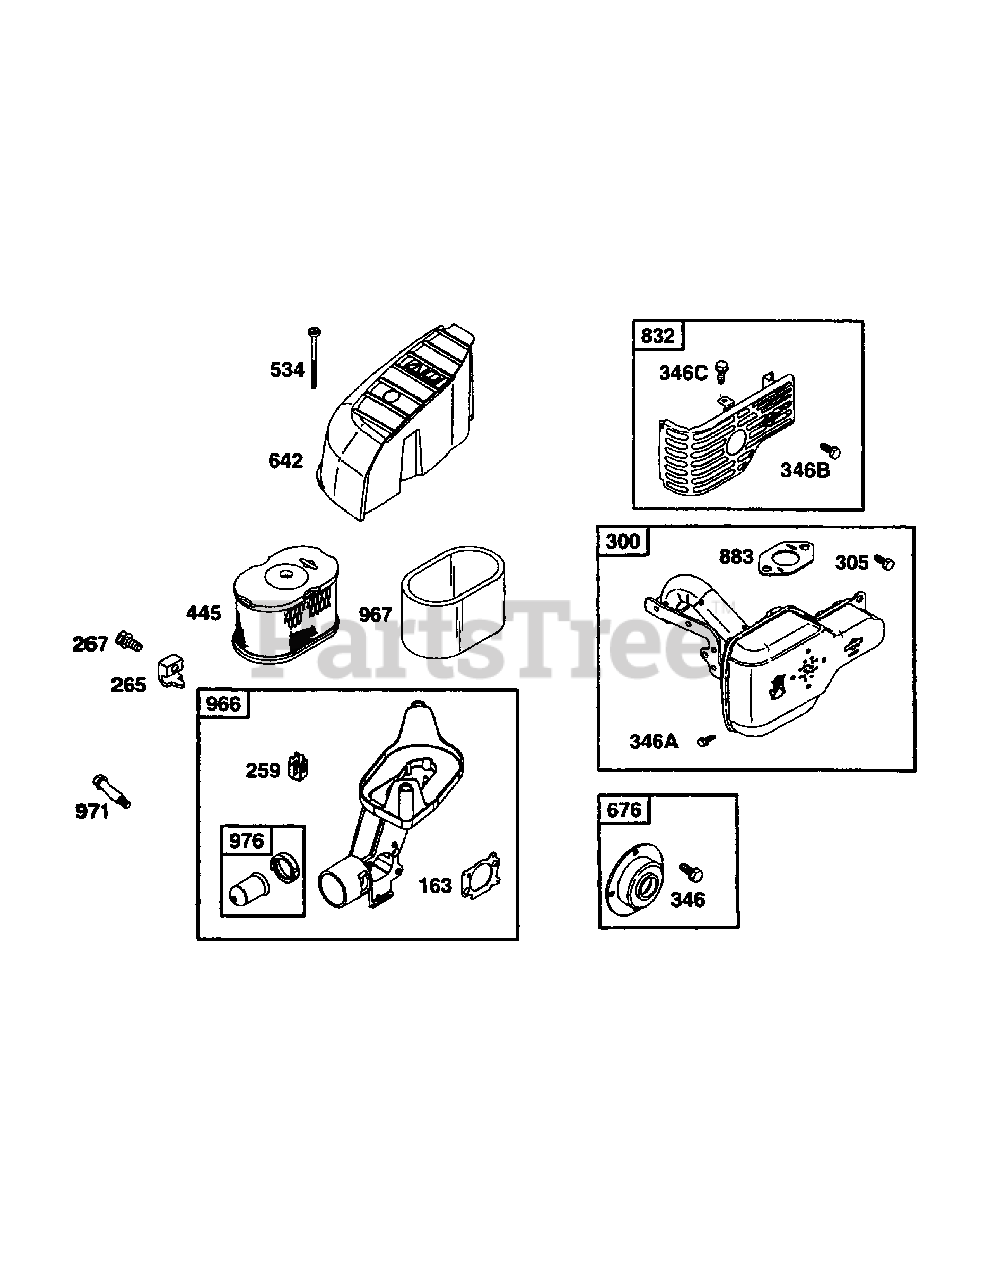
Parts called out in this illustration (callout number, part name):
163	Air Cleaner Gasket
259	Casing Clamp Bracket
265	Casing Clamp
267	Slotted Hex Screw
300	Muffler
305	Hex Screw
346	Hex Screw
346A	Hex Screw
346B	Hex Screw
346C	Hex Screw
445	Air Filter
534	Shoulder Screw
642	Air Cleaner Cover
676	Muffler Deflector
832	Muffler Guard
883	Exhaust Gasket
966	Air Cleaner Base
967	Pre Filter
971	Shoulder Screw
976	Carb Primer
